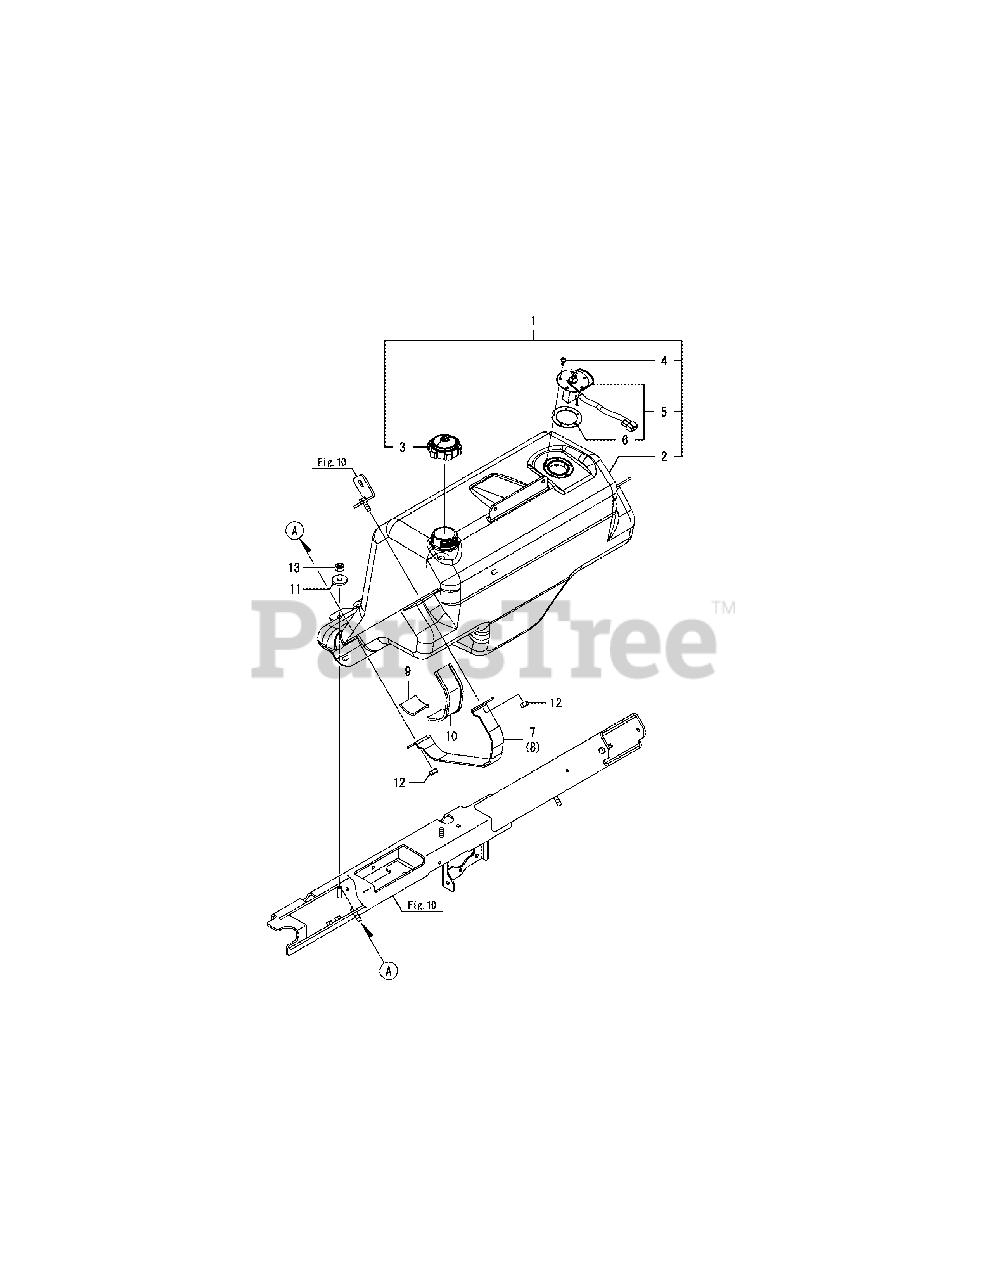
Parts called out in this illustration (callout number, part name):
1	TANK, FUEL ASSY
3	CAP, FUEL TANK
5	FUEL SENDER ASSY
7	BAND, TANK REAR L
8	BAND, TANK REAR R
